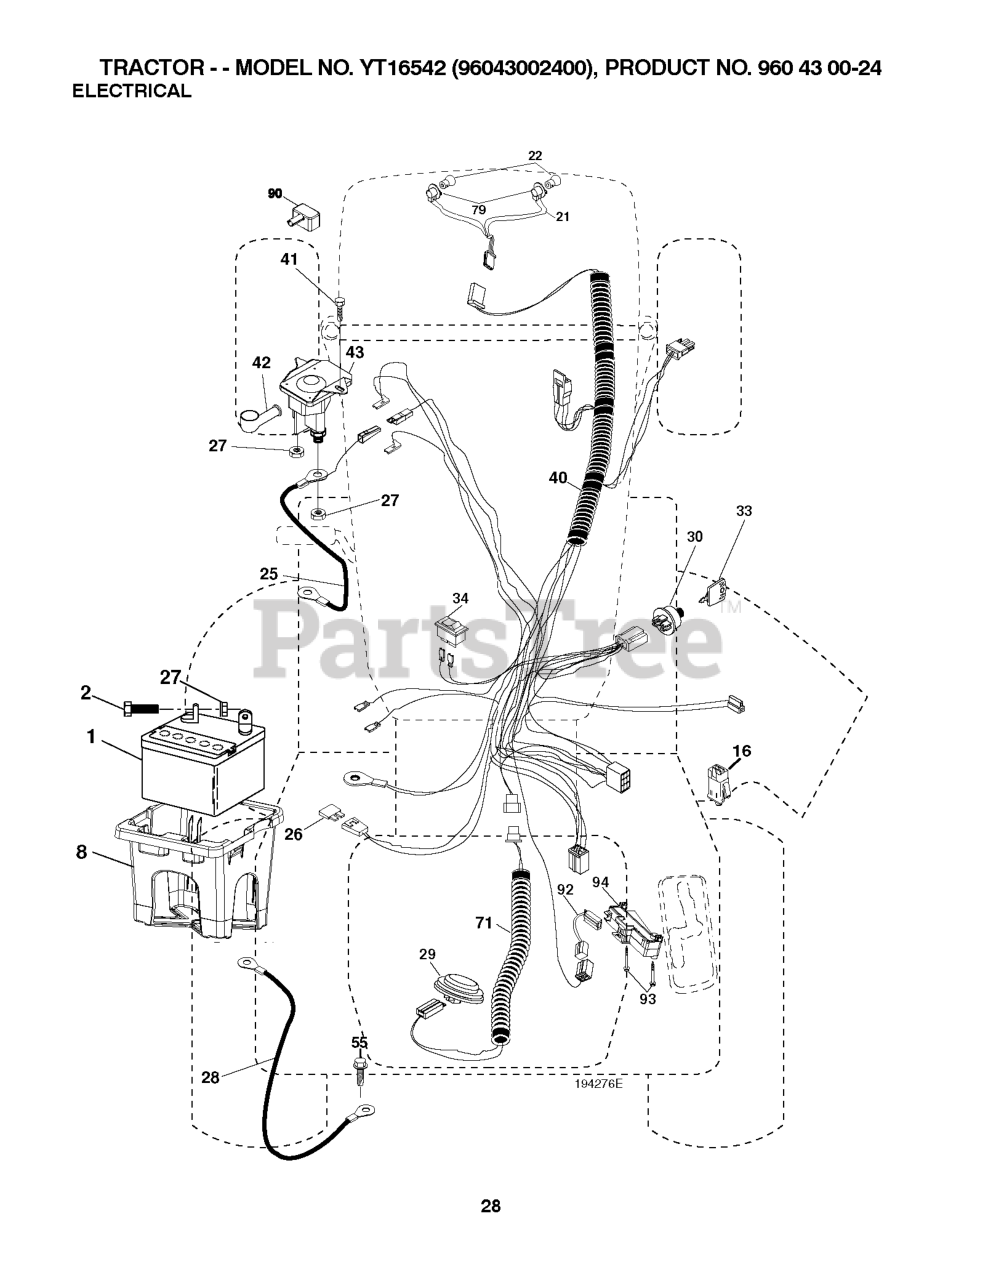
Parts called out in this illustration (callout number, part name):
1	Battery 12 Volt 25 Amp
2	BOLT.HEX.1/4.X.3/4.DICHROMATE
8	BOX.BATTERY.MNT.REAR.L
16	SWITCH INTERLOOK PUSH-IN
21	HARNESS.LIGHT W/4152J BULBS
25	CABLE.STARTER.6GA.RED.
26	FUSE 20AMP
27	NUT
28	CABLE.BLACK.18"REAR.BA
29	SWITCH.SEAT.DP W/RAMPS
30	SWITCH.IGN.DELTA.W.LGH.ROS
33	KEY MLD GEN DELTA
40	HARNESS IGN. DASH
41	SCREW
42	TERMINAL COVER
43	SOLENOID.W/BRASS.PLUNGER
55	SCREW 5/16"
71	HARNESS.IGN.CHASS.TEX.REAR.BAT
79	BULB HOLDER ASM.
90	COVER, TERMINAL BATTERY
92	HARNESS.PIGTAIL.CONSLE
93	SCREW.PLASTITE
94	MODULE.REVERSE.ROS
